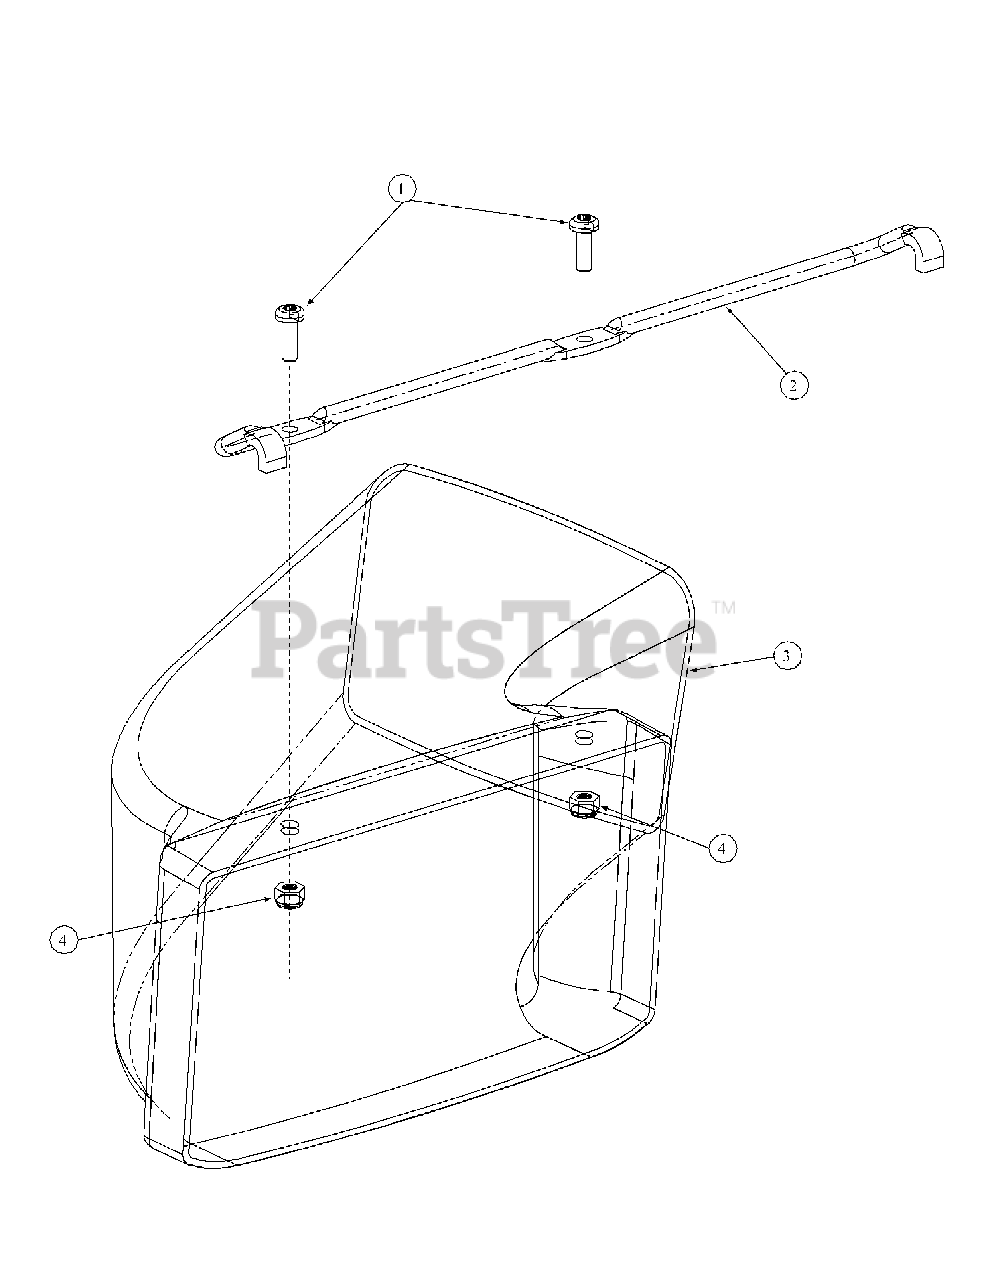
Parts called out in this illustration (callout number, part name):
1	Machine Screw, 1/4-20, .750, PANTRXI
2	21" Side Chute Mounting Rod
3	21" Side Chute Spiral Deck
4	Hex Nut 1/4-20
